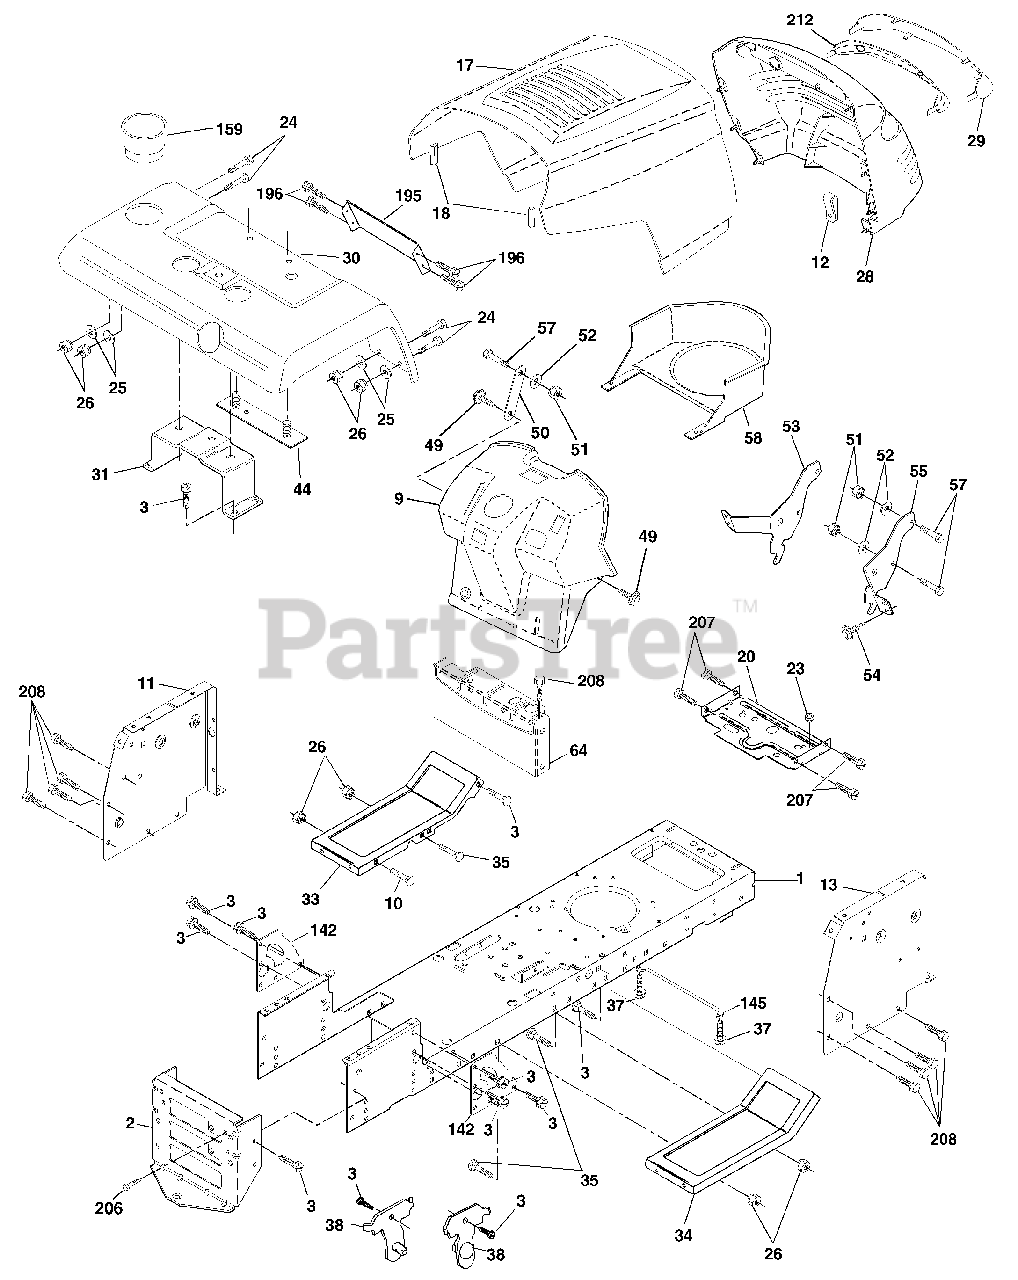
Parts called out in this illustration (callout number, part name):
1	Chassis
2	Drawbar
3	Screw 3/8-16x3/4
10	Bolt Carriage 3/8-16 x 1
11	Panel Dash Lh
12	Clip Tinnerman
13	Panel Dash Rh
17	Hood LT/PL
18	Bumper Hood
20	Plate Mtg Battery Fuel Tank Fr
23	Bushing
24	Bolt Fin Hex 3/8-16 x 1 Gr 5
25	Washer 13/32 X 13/16 X 12 Ga
26	Nut Lock Hex W/Ins 3/8-16 Unc
28	Grille/Lens Asm.
29	Lens P/L
30	Fender Pnt YTGT w/Shift w/fuel
31	Bracket Fender
33	Footrest Pnt Lh
34	Footrest Pnt Rh
35	Bolt Rdhd Sht Sqnk 3/8-16 x 3/4
37	Screw Thdrol 6/16-18 x 1/2 TYT
38	Bracket, Asm. Pivot Mower Rear
44	Strap Asm Fender
49	Screw Hexwsh Thdrol 1/4-20 x 3/4
50	Brace Support Dash P/L
51	Nut Lock Hex W/Ins 1/4-20
52	Washer 9/32 x 7/8 x 16 Ga.
53	Bracjet Grukke Lh
54	Screw Hex Wshd 8-18 x 7/8
55	Bracket Grille Rh
57	Bolt Hex 1/4-20 x 3/4
58	Duct Intake Air
64	Dash Lower STLT
68	Nut Keps Hex 1/4-20 Unc
142	Plate Reinforcement STLT
145	Rod Pivot Chassis/Hood
159	Cupholder
195	Panel Pnt Fender YT/GT
196	Screw Tap Tite 1/4-20 x 1/2
206	Bolt Shoulder 5/16-18
207	Screw Thdrol 5/16-18 x 1/2
208	Screw Thdrol 3/8-16 x 1/2
212	Insert Lens Reflective
